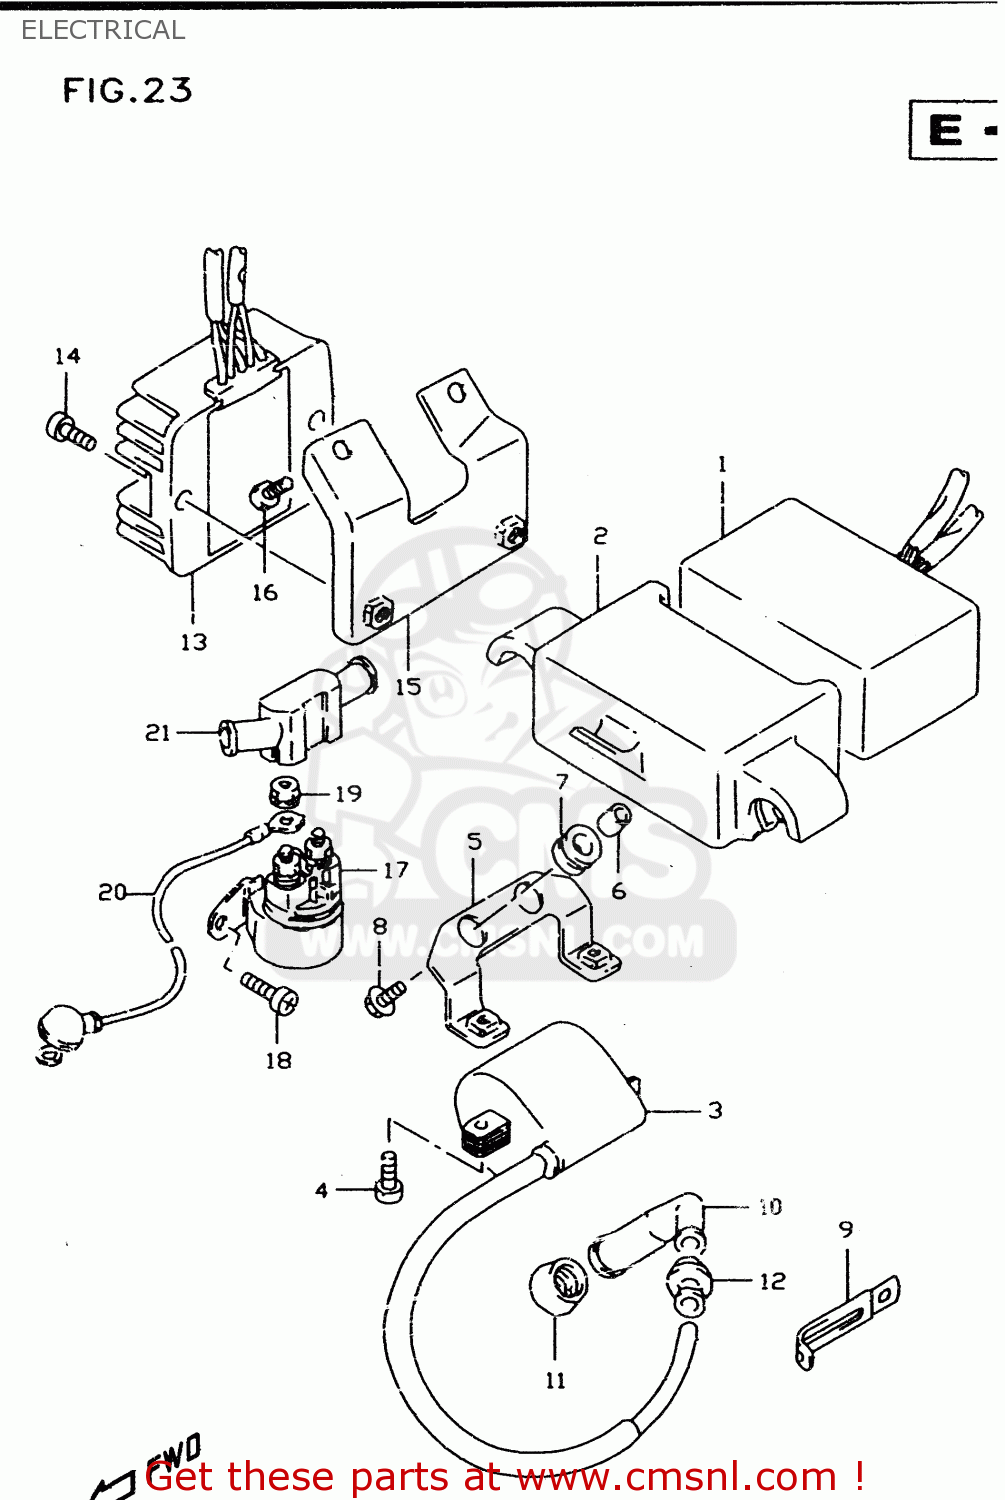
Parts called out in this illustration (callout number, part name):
1	CDI UNIT
2	CUSHION,CDI UNIT
3	COIL ASSY,IGNITION
4	SCREW, 6X20
5	BRACKET,IGNITION COIL
6	SPACER(6.5X9X6.7)
7	CUSHION
8	BOLT
9	CLAMP
10	CAP,SPARK PLUG
11	SEAL,SPARK PLUG
12	SEAL,HIGH TENSION CORD
13	RECTIFIER ASSY
14	SCREW 6X16
15	BRACKET,RECTIFIER
16	BOLT
17	RELAY ASSY,STARTING MOTOR
18	SCREW(6X10)
19	NUT
20	WIRE,STARTER MOTOR
21	CAP,STARTER RELAY TERMINAL
